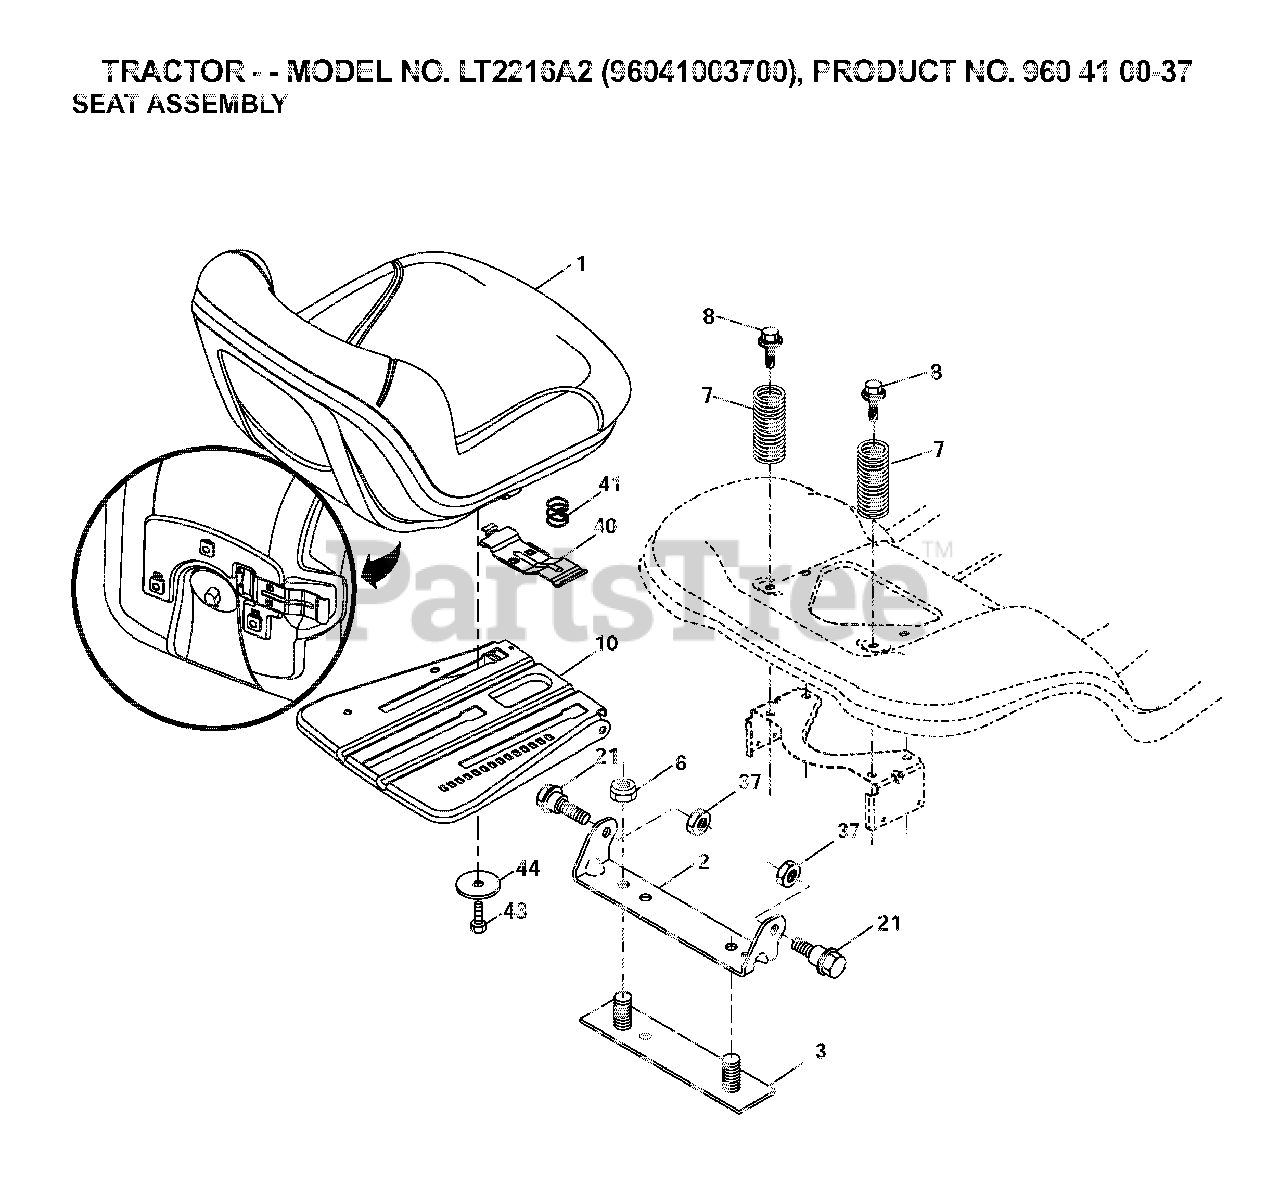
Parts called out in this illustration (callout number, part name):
1	SEAT.TG150.BLK.NLOGO.
2	BRKT.PIVOT.FENDER
6	NUT
7	SPRING COMPRESSION
8	BOLT, 5/16-18 X 1 3/4
10	PAN.ASM.SEAT.3PT
21	BOLT.SHOULDER.5/16-18
37	NUT.71038.31-18.HEX.NYLOCK
40	HANDLE.SLIDE.SEAT.TEX.BLACK
41	SPRING.LATCH.SEAT.TEX
44	WASHER 13/32 X 2-3/8 X 12GA
